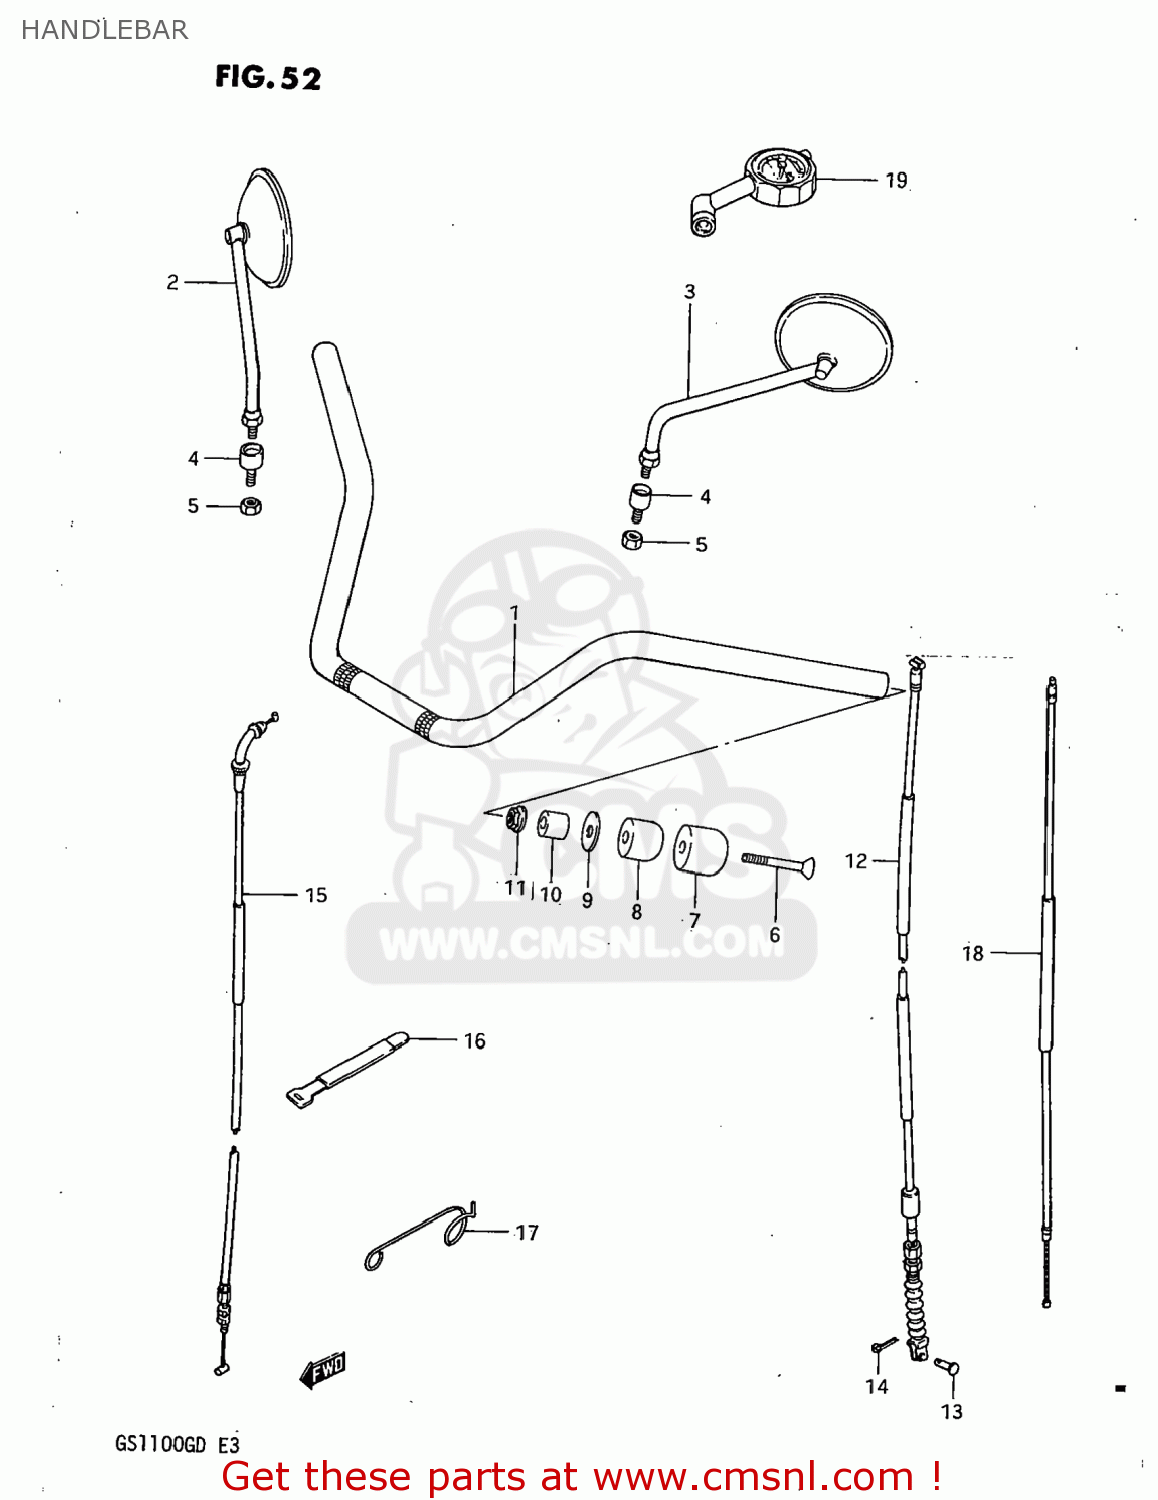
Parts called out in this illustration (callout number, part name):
1	HANDLEBAR
2	MIRROR ASSEMBLY,RIGHT
3	MIRROR ASSEMBLY,LEFT
4	CUSHION,REAR VIEW MIRROR
5	NUT
6	SCREW
7	CAP,BALANCER
8	BALANCER,HANDLE
9	SPACER,BALANCER
10	EXPANDER,HANDLE BALANCER
11	NUT
12	CABLE ASSY,CLUTCH
13	PIN(L:15)
14	PIN
15	CABLE ASSEMBLY,THROTTLE
16	CLAMP
17	GUIDE,CLUTCH CABLE
18	CABLE ASSEMBLY,STARTER
19	GAUGE ASSY,AIR PRESSURE
